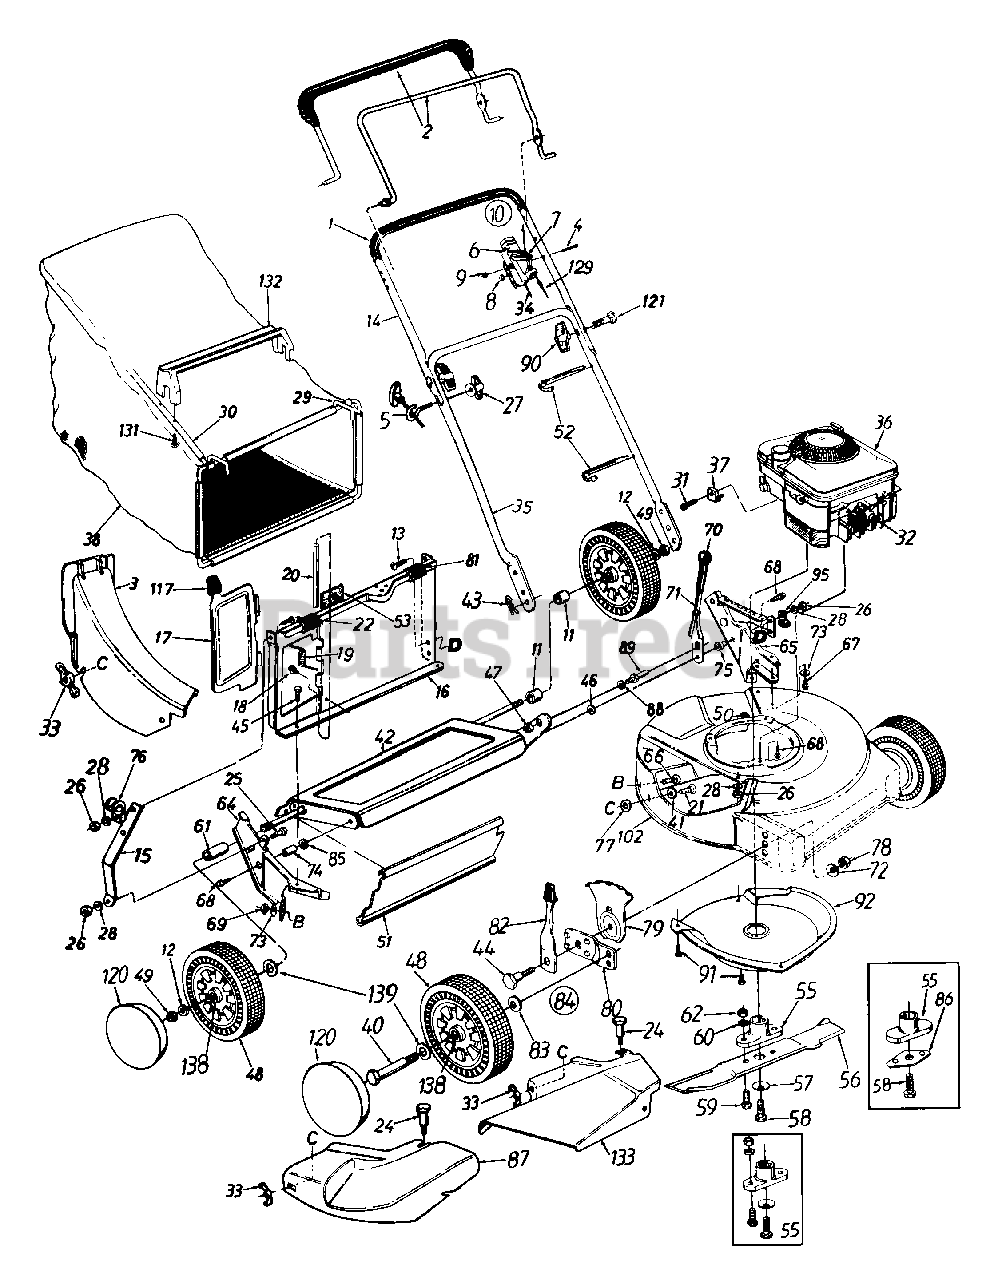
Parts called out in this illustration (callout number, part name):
1	Grip
3	Top Discharge Chute Ass'y.
4	Oval C-Sunk Scr.
5	Rope Guide
6	Throttle Body
7	Throttle Lever
8	Spr. Wash .66" I.D.
9	Hex L-Nut 1/4-20 Thd.
10	Throttle Box Comp.
11	Spacer.526" I.D. x .690" O.D. x .640" Lg.
12	Fl-Wash .510" I.D. x .75"
13	Truss Mach. Scr. 1/4-20 x .62"
19	Torsion Spring
20	Pivot Pin
21	Carriage Bolt 1/4-20 x .62"
22	Truss Mach. Scr. 1/4-20 x .75"
24	Shoulder Bolt .312" Dia. x .18" Lg. Special
25	Hex Bolt 1/4-20 x .62" Lg.
26	Hex Nut 1/4-20 Thd.
27	Handle Knob 1/4-20 Thd.
28	L-Wash. 1/4" I.D.
31	Hex Self-Tap Scr. #10-32 x .62"
32	Spark Plug Insulator
33	Wing Nut w/Washer
34	Throttle Control Wire 61"
36	Engine
37	Cable Clamp
38	21" Top Discharge Grass Bag
40	Shld. Bolt .498" Dia. x 1.45"
41	Fl-Wash .344" I.D. x .62"
44	Shld. Bolt .5" Dia. x .357"
45	Hex AB-Tap Scr. 1/4 x .62"
46	Fl-Wash .38" I.D. x 1.0"
47	Hex Jam Nut 3/8-24 Thd.
48	Wheel Ass'y. Comp. (w/o Ball Bearings)
49	Hex L-Nut 1/2-20 Thd.
51	Rear Flap
52	Cable Tie
53	Foam Strip 1" Lg.
55	Blade Adapter Kit
56	21" Mulching Blade
57	Bell-Wash .39" I.D.
58	Hex Bolt 3/8-24 x 1.5" Lg.
59	Hex Bolt 3/8-24 x 1" Lg.
60	L-Wash. 3/8" I.D.
61	Sleeve .526" I.D. x .69"
62	Hex Nut 3/8-24 Thd.
67	Hex Wash. Hd. B-Tap Scr. 5/16-18
68	Hex Wash. Hd. TT-Tap Scr. 3/8-16
69	Hex Nut 5/16-18 Thd.
71	Height Adj. Lever
72	Bell-Wash .39" I.D. x 1.38" O.D.
73	Bell-Wash. 5/16" I.D.
74	Spacer .383" I.D. x .503" O.D.
75	Shld. Spacer .500" Dia.
76	Rope Guide
77	Bolt Retainer 1/4 x .50" O.D.
78	Hex Nut 3/8-16 Thd.
79	Height Adj. Plate
81	Panel Clip
82	Spring Lever Ass'y. w/Knob
83	Bell-Wash .38" I.D. x .88" O.D.
84	Height Adj. Ass'y. Comp.- R.H.
85	Fl-Wash. 3/8" I.D. x 1" O.D.
86	Blade Bell Support
87	Mulching Plug
88	L-Wash. 3/8" I.D.
89	Shld. Pin 3/8-24 x 1.43" Lg.
90	Hand Knob
91	Hex Wash. Hd. Tap Scr. 1/4 x .38" Lg.
120	Hub Cap
121	Curved Hd. Bolt 5/16-18 x 2" Lg.
129	Control Cable - 44" Lg.
131	Hex AB-Tap Scr. #12 x 1.0"
132	Bag Handle
133	Side Chute Deflector Ass'y.
138	Ball Bearings
139	Wave Washer
